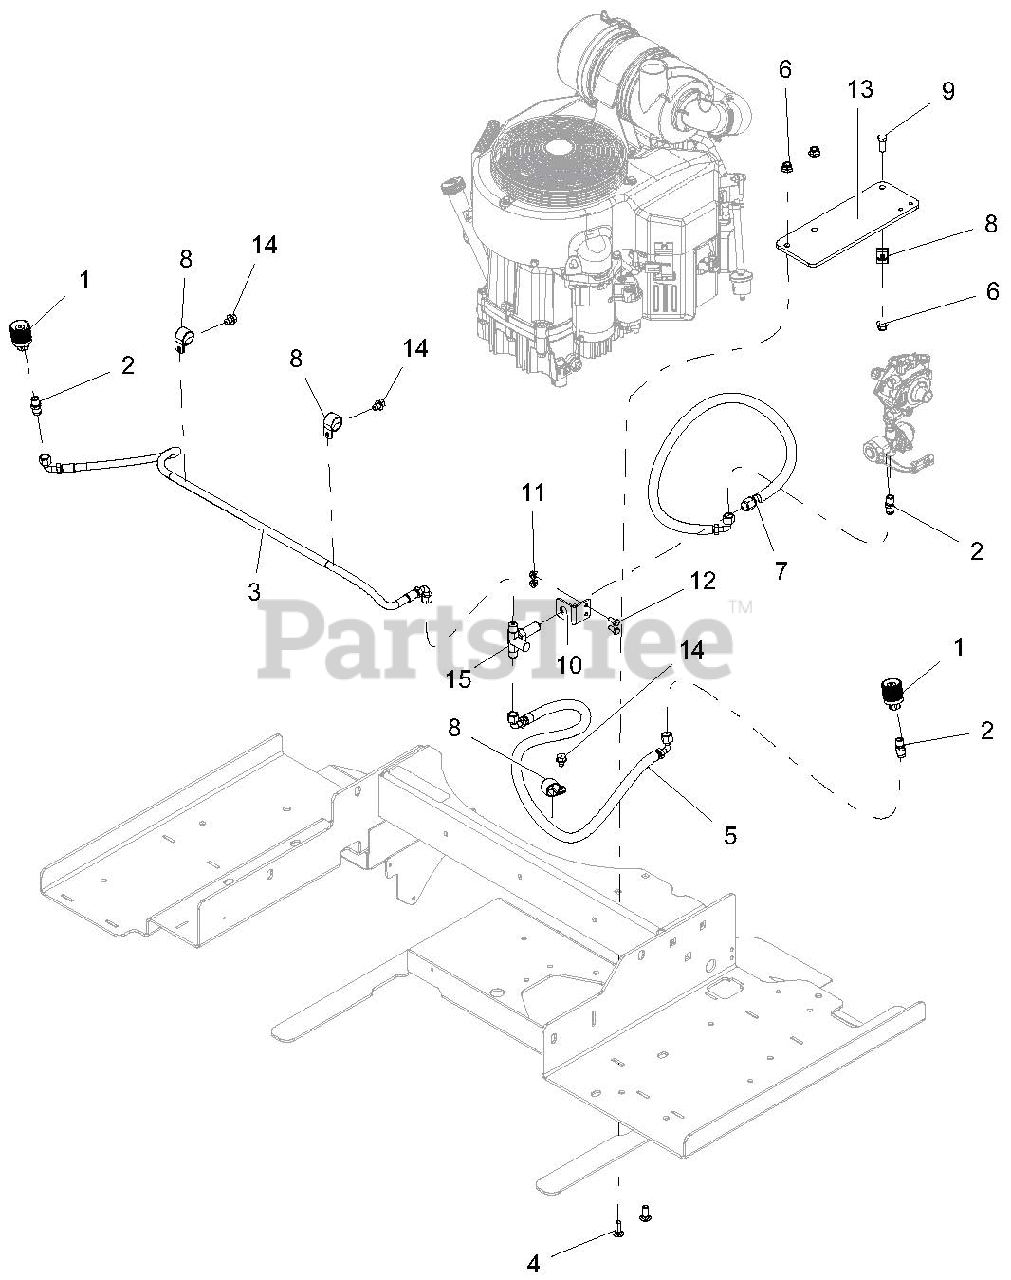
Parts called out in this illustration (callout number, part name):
1	FTG, LPG TANK COUPLER -LH THRD
2	FTG, ADPTR 1/4MNPT X 5/8MJIC
3	HOSE, LPG SS25UL-6-4-6-45"
4	BLT-RDHDSQNK .38-16X1.00 G5 YWZC
5	HOSE, LPG SS25UL 6-4-6-45"
6	NUT-LK-NYL-FLG .38-16 YWZC
7	HOSE, LPG SS25UL 6-4-6-30.00
8	CLAMP, CUSHIONED STEEL REV
9	BLT-HEX .38-16X1.00 GR5 YWZC
10	BRKT, TEE VALVE- MOUNTING
11	NUT, LK-TOP-FLG .25-20 YWZC
12	BLT-HEX .25-20X.63 GR5 YWZC
13	PLATE, REGULATOR MOUNT, E
14	SCR-TAP .38-16X.50 HWH TR YWZ
15	VALVE, SHERWOOD T PV3866 LPG
